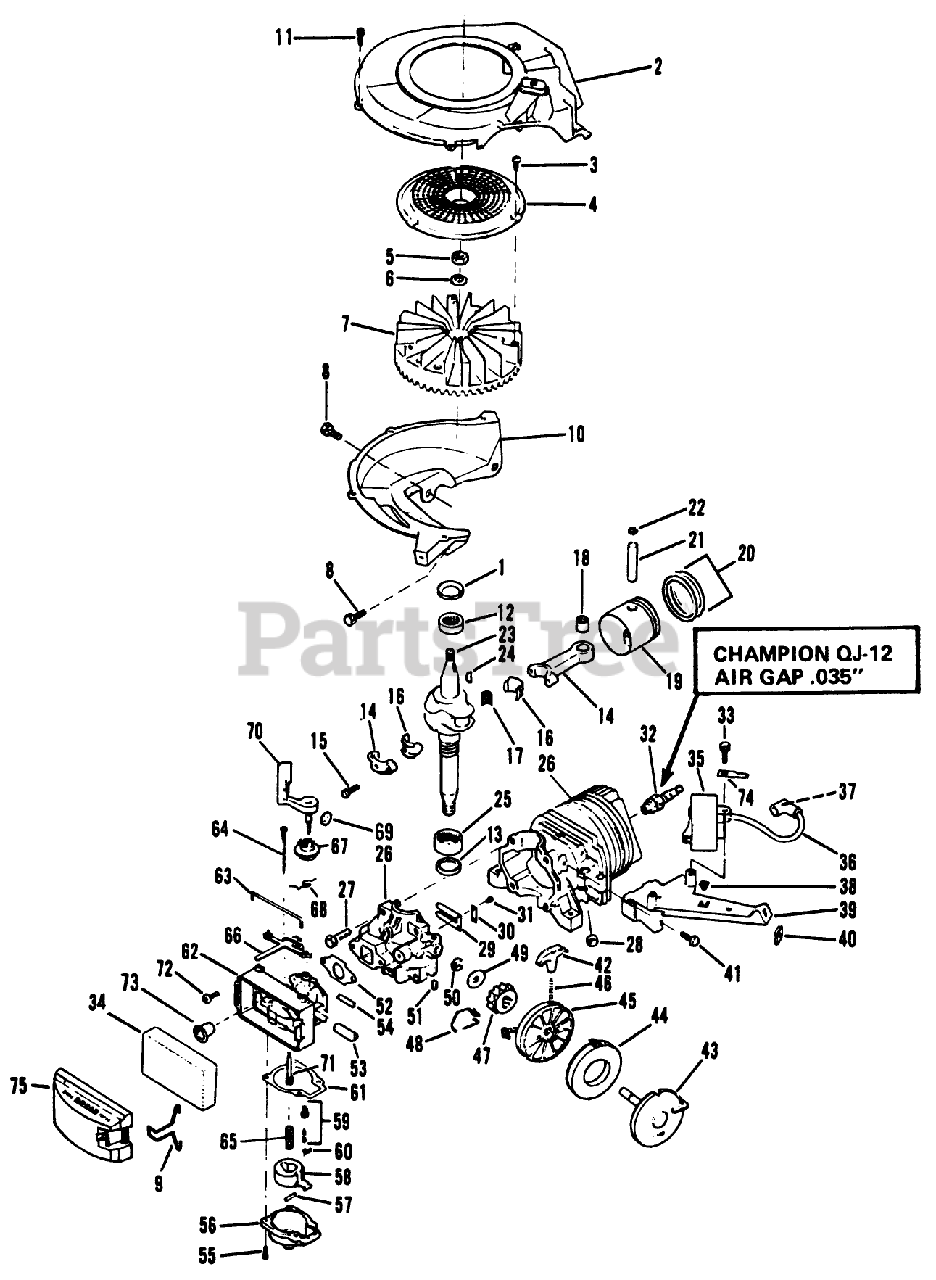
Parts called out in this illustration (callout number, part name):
2	AIR BAF&EYELET S
3	SCREW F
5	NUT
8	SCREW-SEMS
9	RETAINER-COVER, FILTER
10	SHROUD BASE S
11	SCREW S
12	BEARING V
13	SEAL-OIL
15	SCREW-HSH
16	LINER ASM
18	BEARING AY F
22	RING-RETAINING
24	KEY
25	BEARING V
27	SCREW S
28	PLUG-CORE VF
30	PLATE-BACKUP, REED
36	HT LEAD&COVER XEV
38	NUT-CLIP
40	NUT - SPEED S
42	HANDLE STARTER S
45	PULLEY STARTER S
48	SPRING F
49	WASHER S
52	GASKET CARB S
54	TUBING PRIMER S
55	SCREW-HH
62	CARB BODY S
63	RETAINER
64	NEEDLE ADJ. AY S
65	FILTER-FUEL VS
66	LEVER S
67	COLLAR-ADJUST, AIRVANE
68	SPRING,THROTTLE S
69	DISC S
70	AIR VANE&SHAFT S
72	SCREW
74	TERMINAL S
